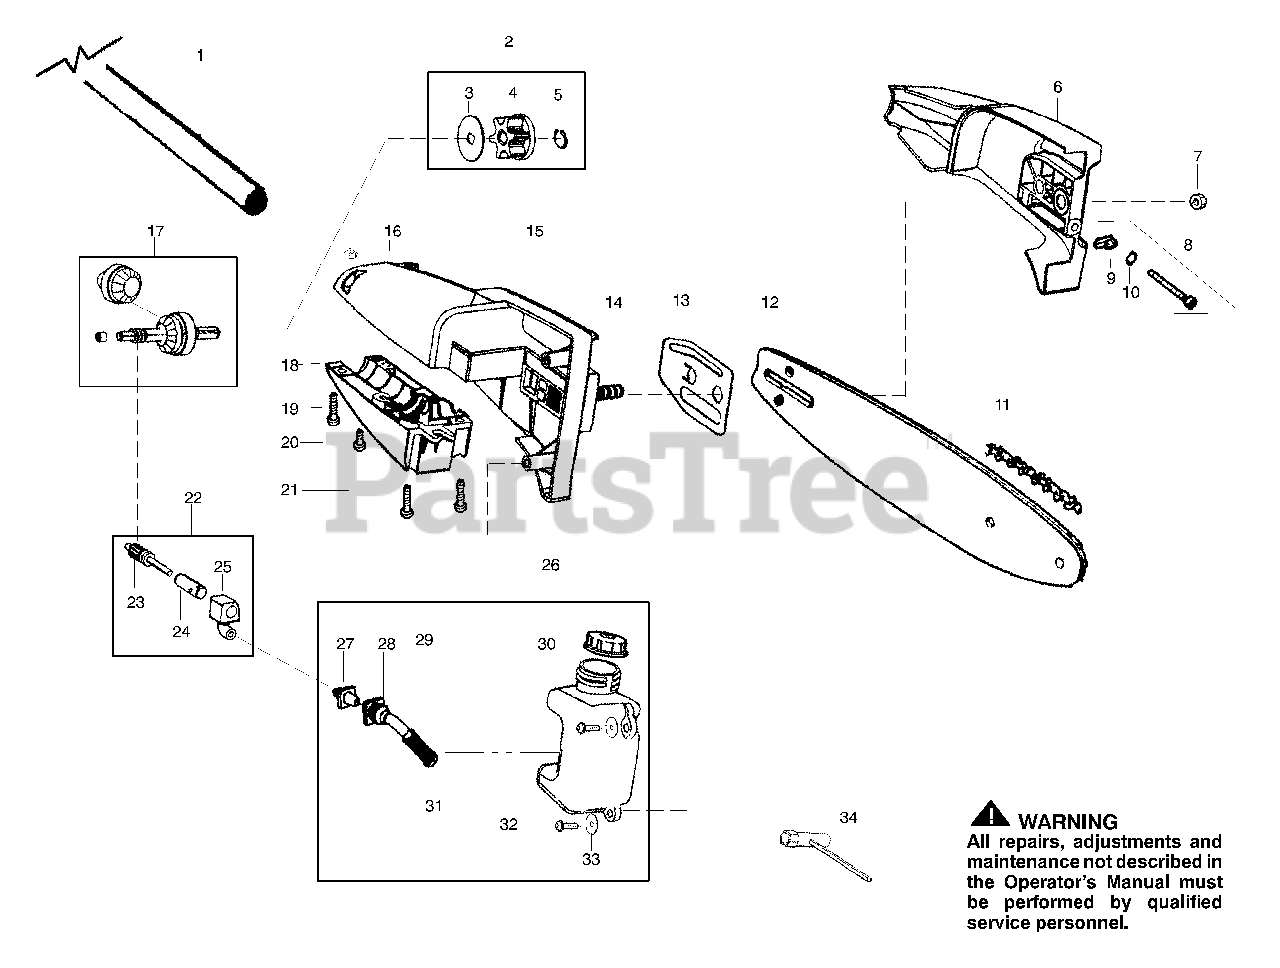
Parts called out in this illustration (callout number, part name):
1	Assy-Driveshaft
2	Kit-Sprocket Assy.
4	Sprocket
5	Retainer-Sprocket
6	Assy-Bar Clamp
7	Nut-Bar Mounting
8	Kit-Bar Adjust
9	Pin-Bar Adjust
10	Retainer-Bar Adjust
11	Chain-8"
13	Plate-Bar pad
14	Bolt-Bar
15	Hsg.-Upper
17	Kit-Gear Assy
18	Hsg.-Lower
20	Screw-Align
22	Kit-Oil Assy
23	Assy-Gear Plunger
25	Block-Oil
26	Assy-Oil Tank
27	Fitting-Oil Line
28	Intake-Oil Line
29	Filter-Oil
30	Cap-Oil
31	Plug-Oil Filter
34	Wrench-Bar
